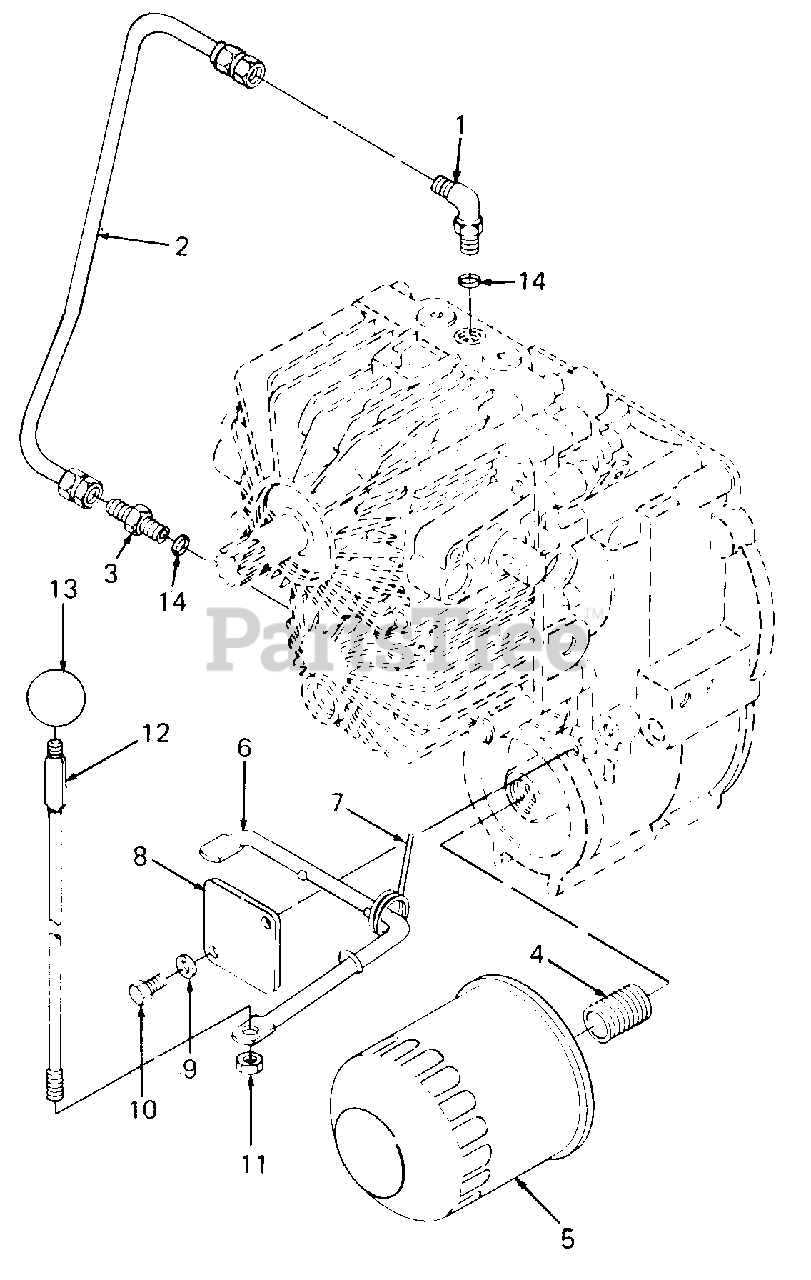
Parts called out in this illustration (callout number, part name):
1	Elbow, 90 Degree Tube
2	Line, Metal Pickup
3	Connector, 37 Degree Tube
4	Nipple, Oil Filter
5	Filter, Oil
6	Rod, Dump Valve Lower
7	Spring, Torsion
8	Plate, Retaining
9	Washer, Lock, 1/4
10	Screw, Hex Cap, 1/4-20 X .50 Lg GR5
11	Nut, Hex Top Lock, 1/4-20
12	Rod, Dump Valve Upper
13	Knob, Ball
14	O-Ring, 3/8 OD Tube
